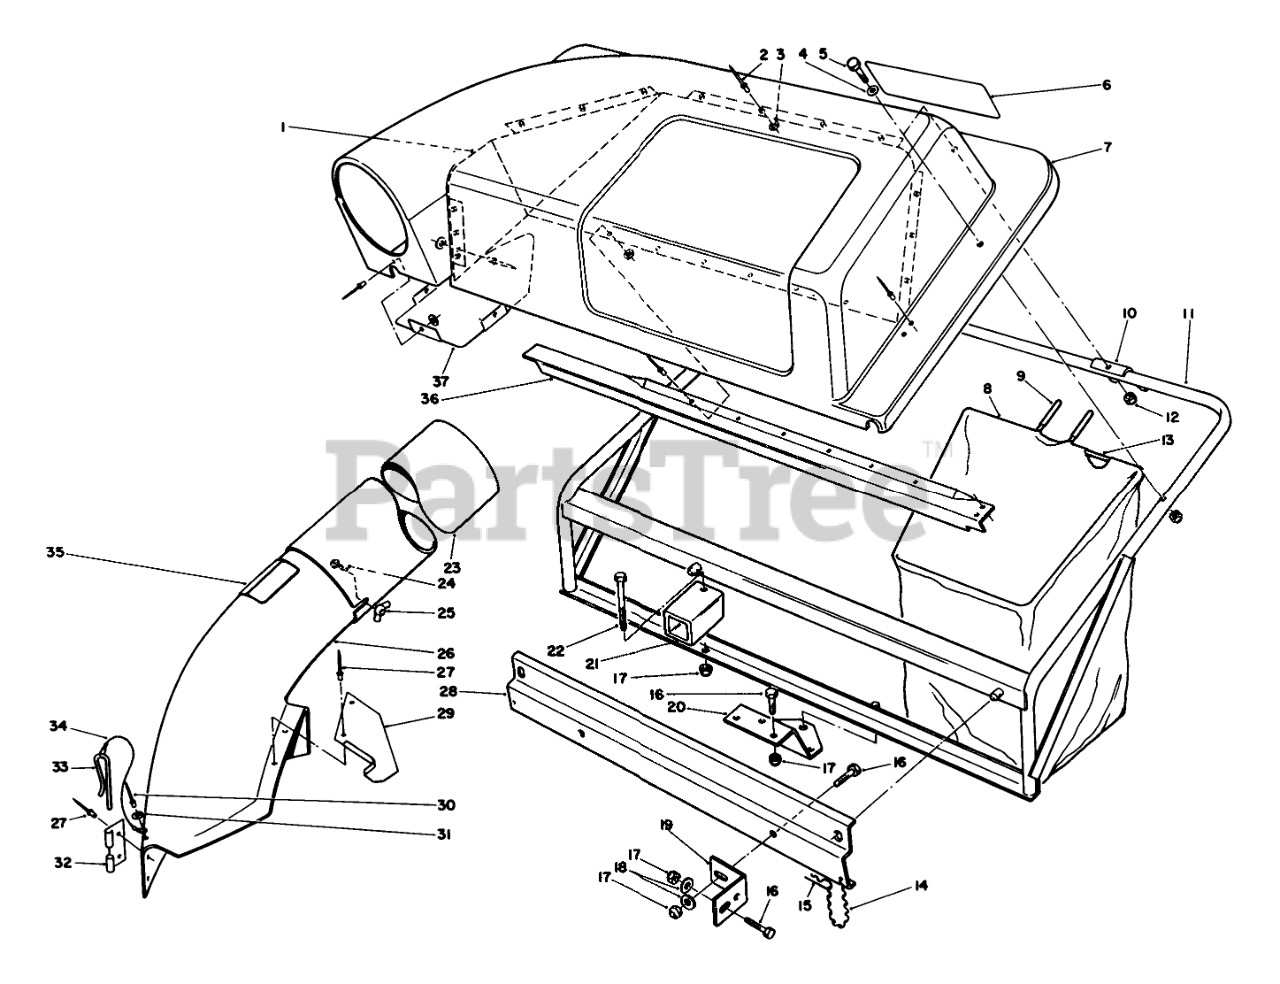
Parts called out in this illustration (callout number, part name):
1	Screen Cover
2	RIVET-POP
3	WASHER-FLAT
4	WASHER-PLAIN
5	SCREW-HH
6	TWIN BAGGER DECAL
7	Cover
8	Bag-Twin Bagger (Incl. Ref. #9 & 13)
9	GRIP-HANDLE, BAG
10	BAG FRAME BRKT
11	Frame
12	NUT-LOCK, CAP
13	Frame-Bag
14	6-LINK CHAIN W/HOOK
15	PIN-HAIR
16	SCREW-HH
17	NUT-LOCK, NI
18	WASHER-PLAIN
19	MTG BRACKET
20	MTG PLATE B
21	FRAME SUPT TUBE B
22	SCREW-HH
23	TUBE(ROUND&LONG)
24	BOLT-CARR
25	NUT-WING SPECL
26	Chute Assembly (Incl. Ref. #27, 29-35)
27	RIVET-BLIND
28	Bracket Frame Support
29	CHUTE SUPT BRKT
30	RIVET-BLIND
31	WASHER-PLAIN
32	BRACKET-MOUNTING, CHUTE
33	PIN-LOCKING, CHUTE
34	LANYARD
35	DECAL-DANGER
36	SCREEN SUPT BRKT B
37	Shield Cover
